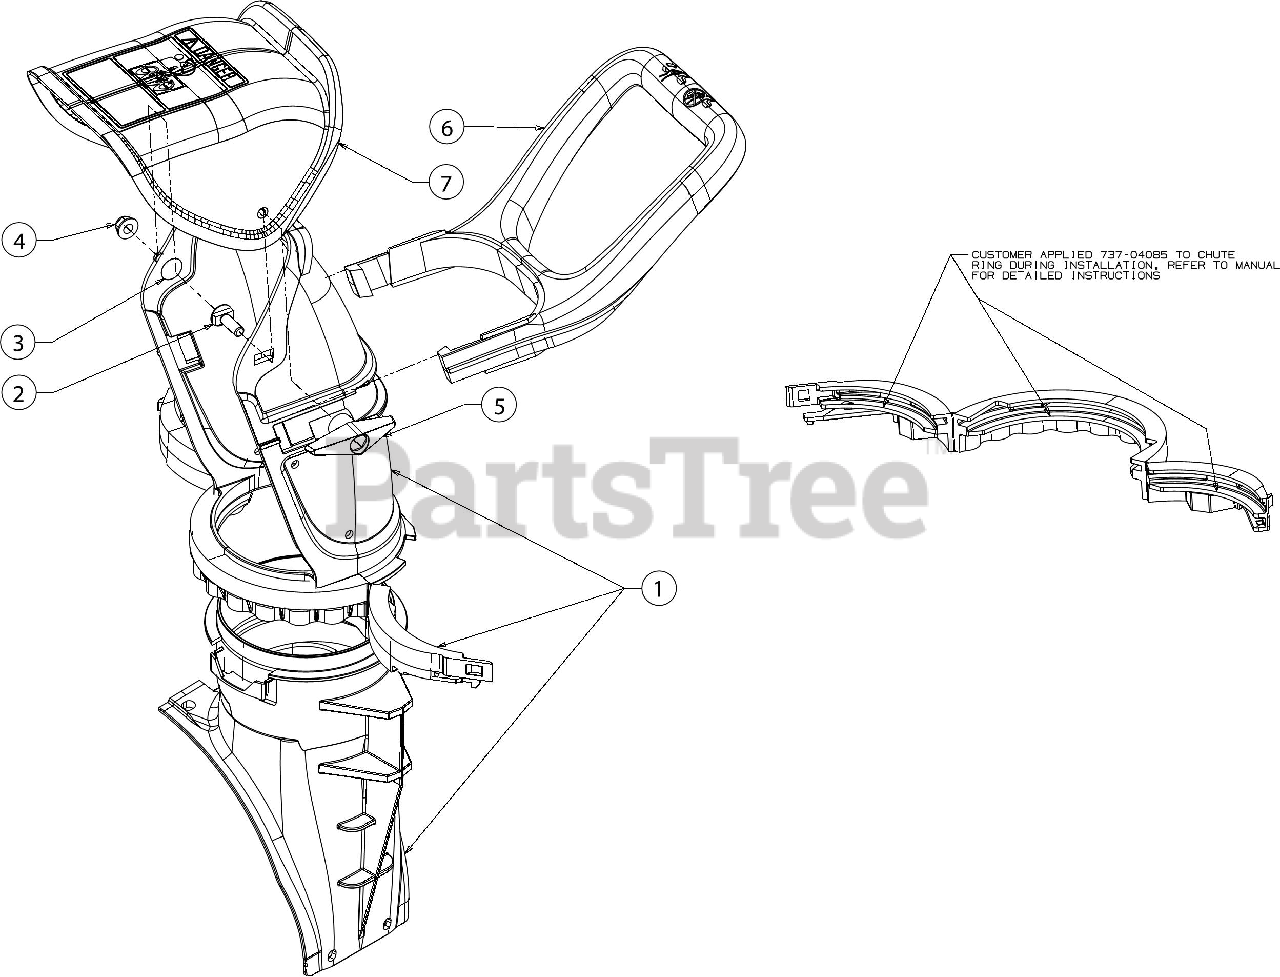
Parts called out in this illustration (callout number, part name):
1	CHUTE ASSEMBLY
2	CARRIAGE BOLT 5/16-18 x 1
3	CARRIAGE BOLT 5/16-18 x .75
4	FLANGE LOCK NUT 5/16-18
5	WING NUT KNOB
6	CHUTE HANDLE
7	UPPER CHUTE
8	LITHIUM GREASE
